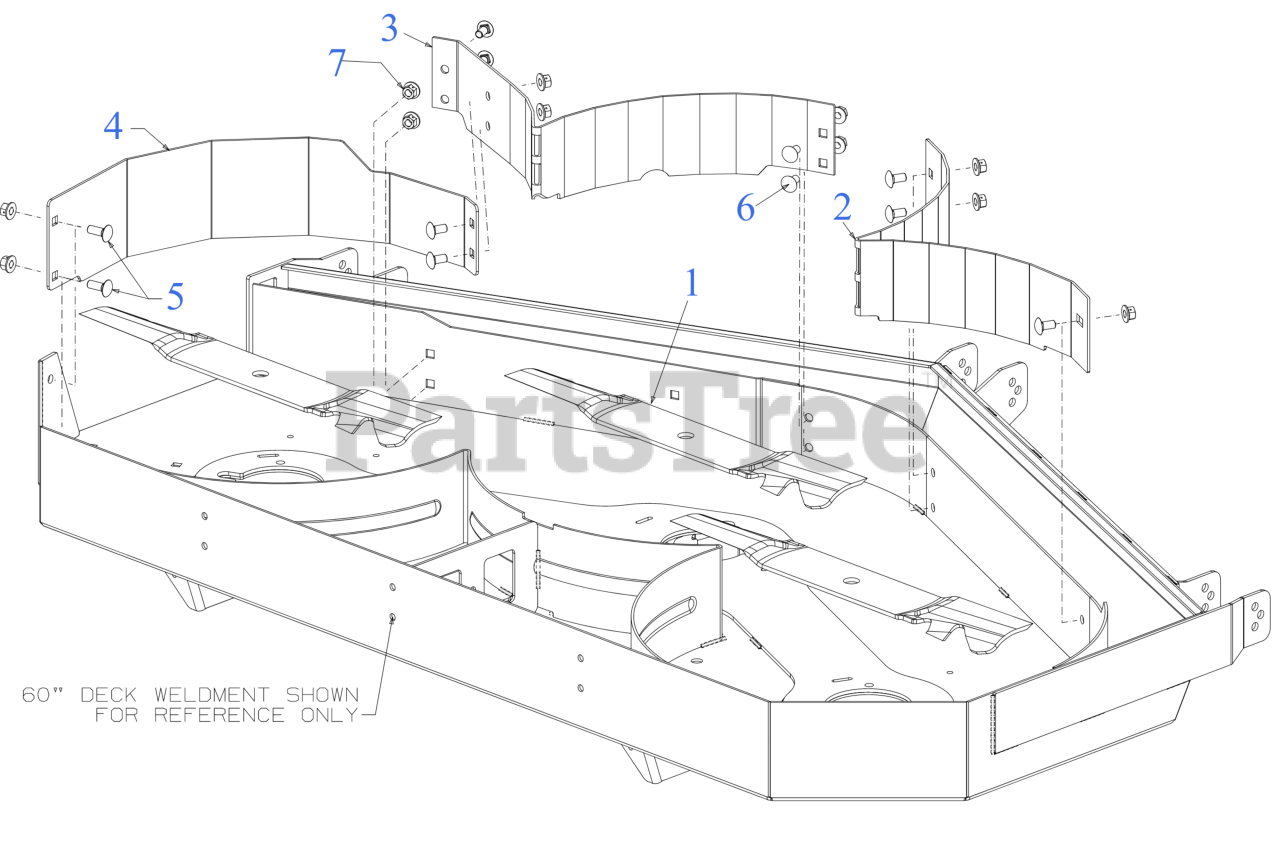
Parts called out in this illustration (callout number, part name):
1	21" XTREME BLADE
2	MULCH BAFFLE (LEFT)
3	MULCH BAFFLE (CENTER)
5	CARRIAGE BOLT 3/8-16 x 1.00 GR5
6	CARRIAGE BOLT 3/8-16 x .75
7	NUT-CTRLCK FLG HEX
